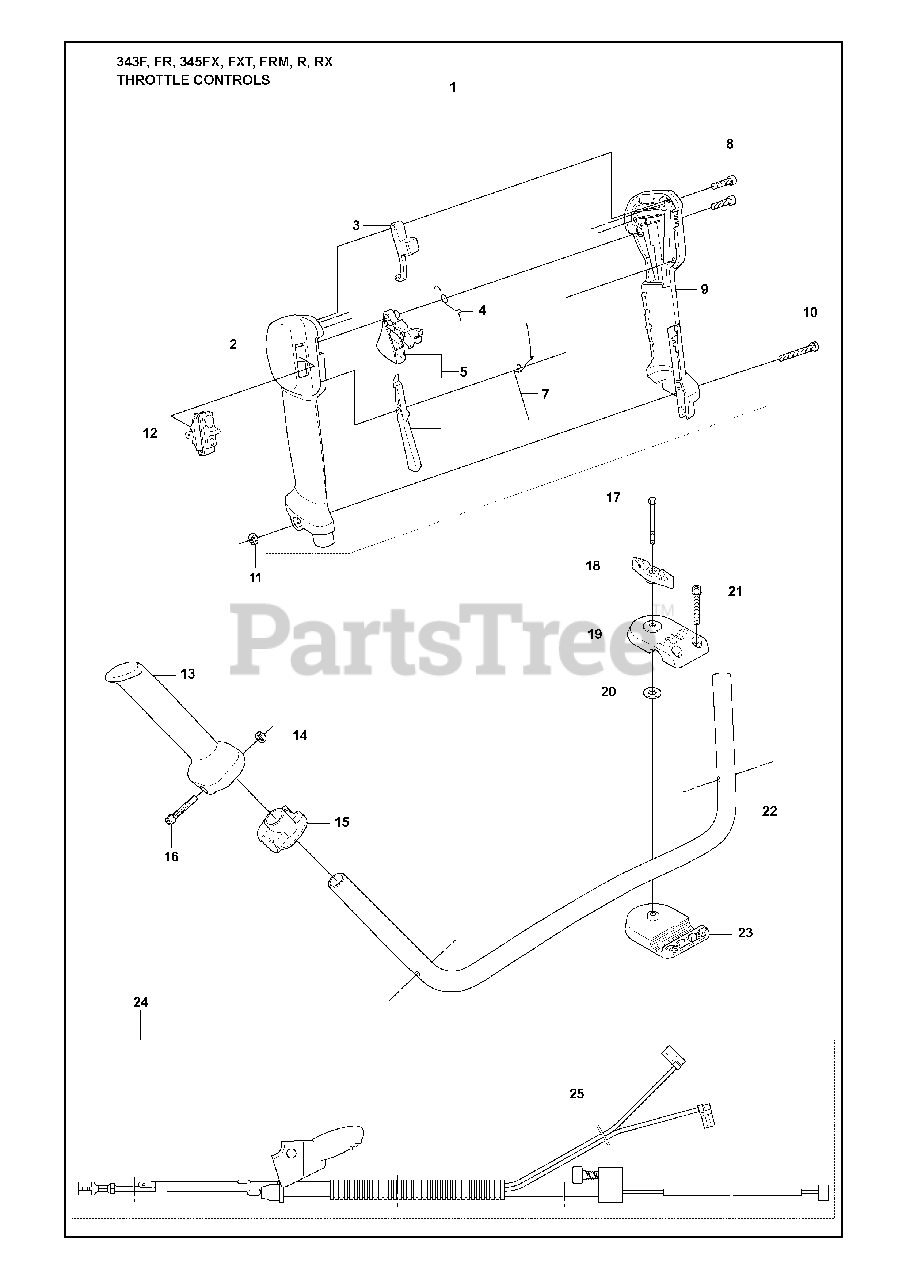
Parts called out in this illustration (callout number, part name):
1	THROTTLE HANDLE ASSY
2	HANDLE HALF LEFT
3	LOCKOUT STARTER THROTTLE
5	THROTTLE CONTROL
9	HANDLE HALF RIGHT
10	%SCREW
12	STOP BUTTON
14	NUT M6M M5
17	%SCREW
19	HANDLE HOLDER UPPER
23	HANDLE HOLDER LOWER
24	WIRING ASSY
25	SCREW
